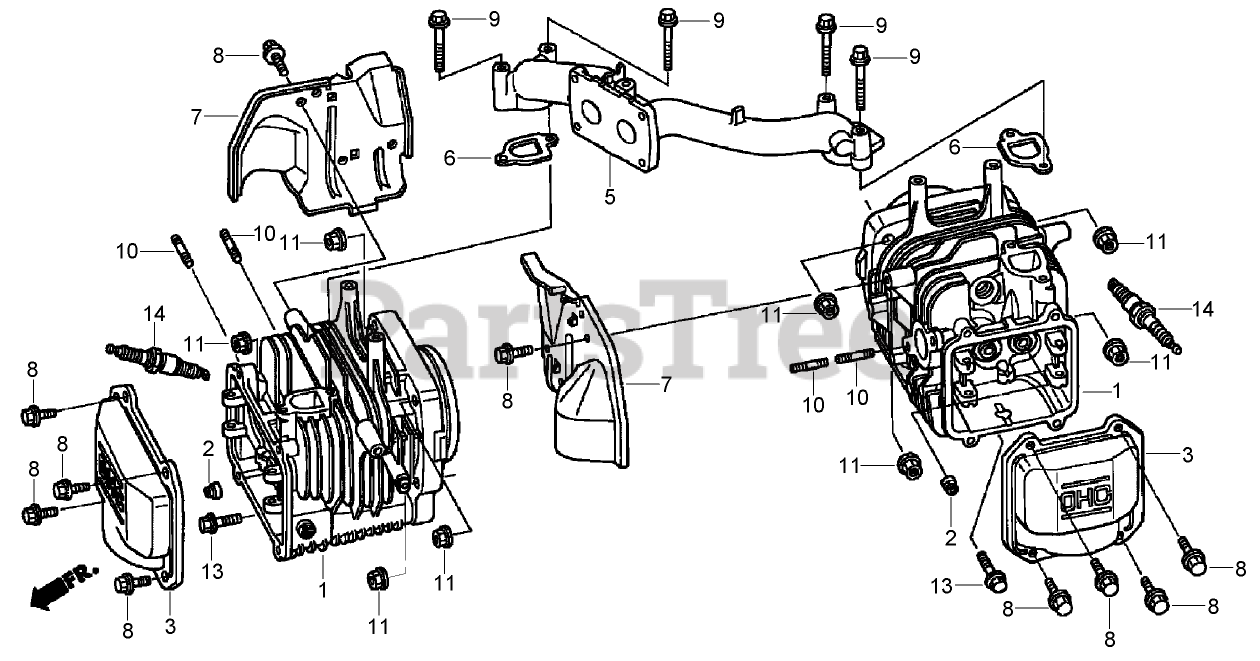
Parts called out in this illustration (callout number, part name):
1	CYLINDER
2	SEAL-STEM, VALVE
3	COVER-HEAD
5	MANIFOLD-INTAKE
6	GASKET-MANIFOLD, INTAKE
7	SHROUD
8	BOLT-FLANGE (6X12) (C T200)
9	BOLT-FLANGE (6X45) (C T200)
10	BOLT-STUD (6X28)
11	NUT-FLANGE (8MM)
13	BOLT-FLANGE (6X30)
14	SPARK PLUG (B P R4E S) (N G K)
14	SPARK PLUG (W14E P R-U) (DENSO)
14	SPARK PLUG (B P R 5E S) (N G K)
14	SPARK PLUG (W16E P R-U) (DENSO)
